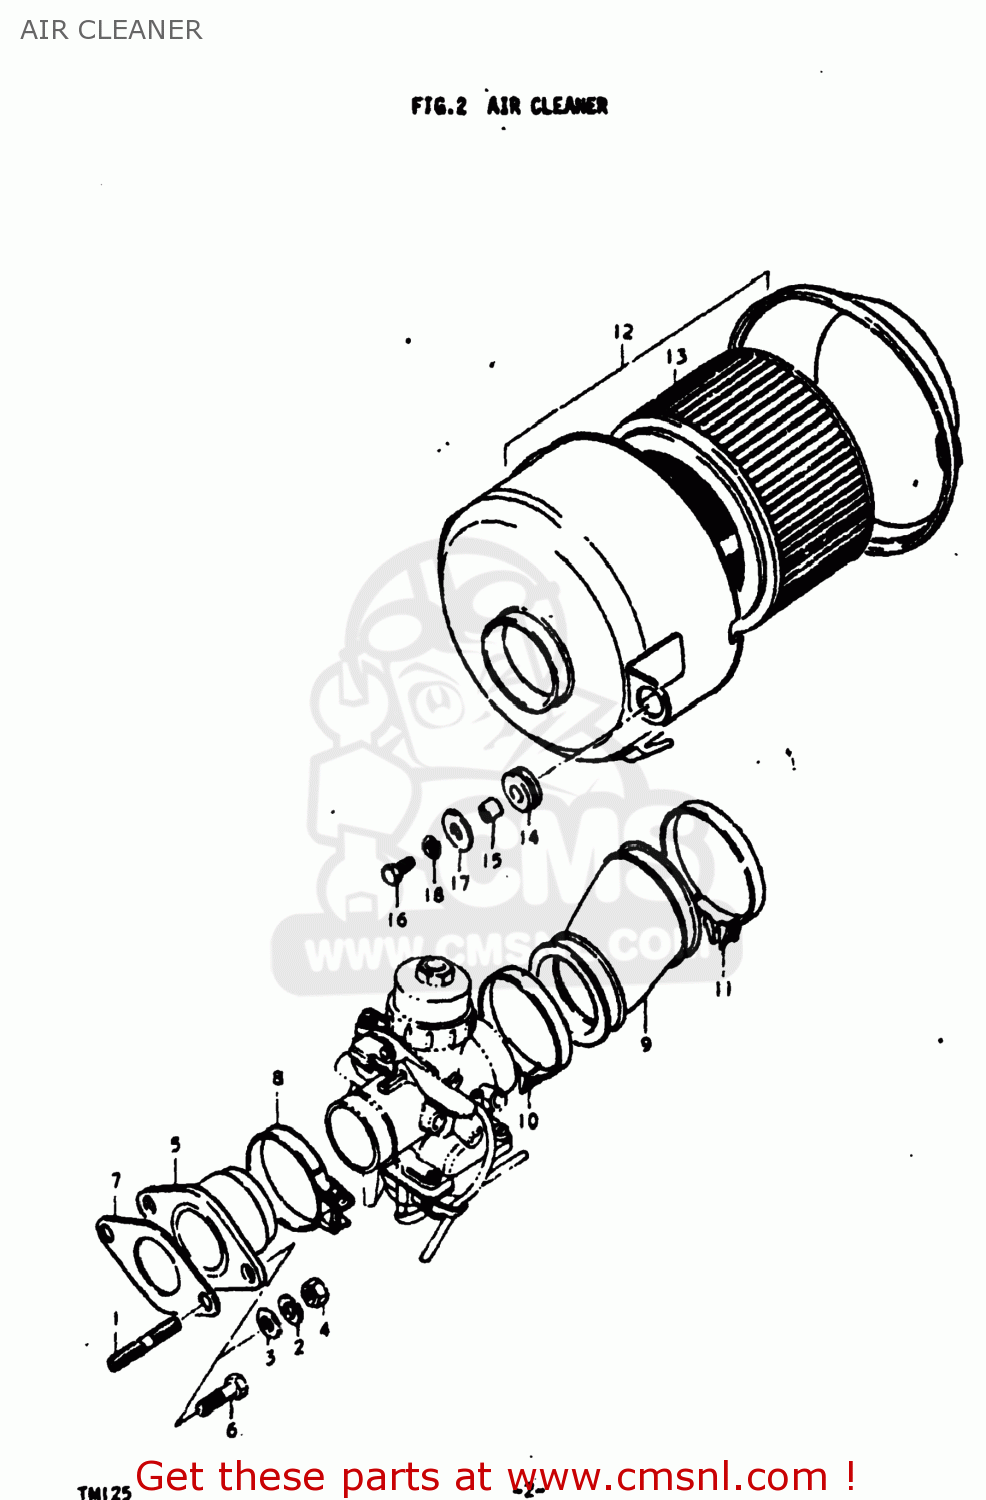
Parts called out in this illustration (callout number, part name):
1	STUD BOLT
2	LOCK WASHER
3	WASHER
4	NUT
5	PIPE,INTAKE
6	BOLT
7	GASKET,CARBURETOR (MCA)
8	CLAMP
9	HOSE,CARBURETOR AIR INLET
10	CLAMP
11	CLAMP
12	CLEANER ASSEMBLY,AIR
13	FILTER,AIR CLEANER
14	CUSHION
15	SPACER (7X9X7)
16	BOLT
17	WASHER (6.5X20X1.2)
18	LOCK WASHER
